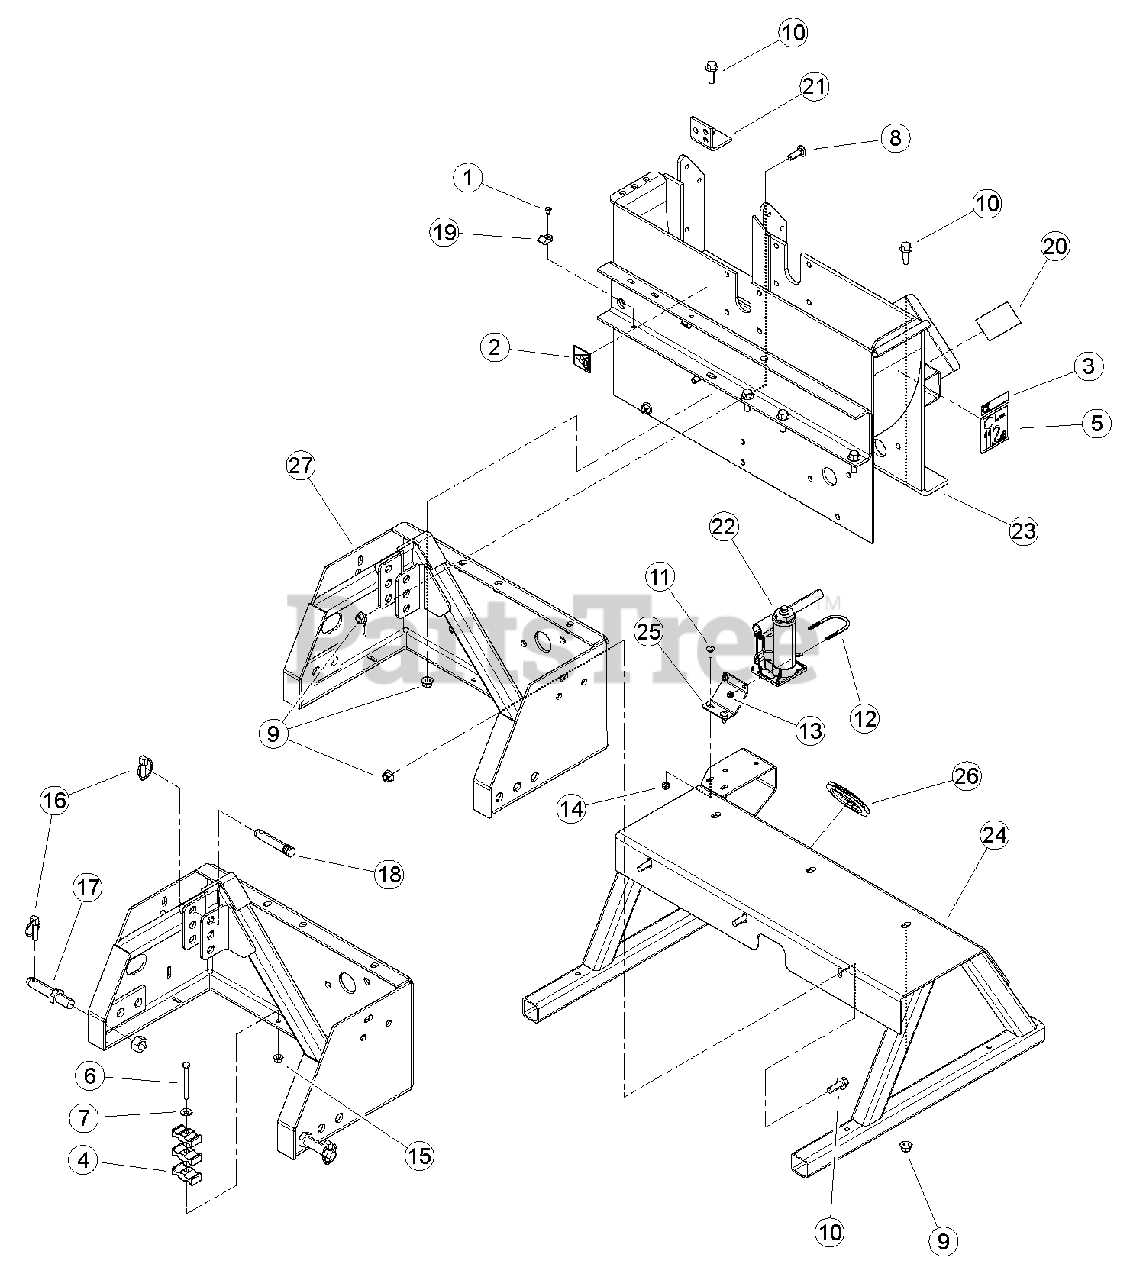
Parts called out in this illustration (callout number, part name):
1	RIVET, 1/4 X 3/4 ST POP
2	DECAL, SHIELD DANGER ISO
3	DECAL,CH9540 INFORMATION (CE COMPLIANT ONLY)
4	CLAMP, PLASTIC HOSE
5	DECAL, 112 DB (CE COMPLIANT ONLY)
6	BOLT, 3/8 X 3-1/2" HEXHD GR5 ZP
7	WASHER, 3/8" FLAT ZP
8	BOLT, 1/2 X 1-1/2" GR5 CRG ZP
9	NUT, 1/2-13 NYLOCK FLANGE
10	BOLT, 1/2-13 X 1-1/2 GR5 FLANGE NC
11	BOLT, 5/16 X 7/8" GR5 CRG NC ZP
12	U-BOLT, 1/4 X 1-1/2 PIPE
13	NUT, 1/4-20 NYLOCK-FLANGE
14	NUT, 5/16-18 NYLOCK-FLANGE
15	NUT, 3/8-16 NYLOCK FLANGE
16	PIN, 7/16 X 1-3/4 LYNCH
17	PIN, LIFT ARM 7/8 X 5" LG
18	PIN, TOP LINK 3/4 X 4-1/2" LG
19	CLAMP, CABLE MOUNT
20	DECAL, FEED SPEED
21	ANGLE, LOWER SHOCK
22	JACK, HYDRAULIC 2 TON
23	WELDMENT, CHIPPER BOTTOM
24	WELDMENT, PTO STAND
25	PLATE, JACK MOUNT
26	TRIM, SLOT EDGE COVER
27	WELDMENT, HITCH SUPPORT
